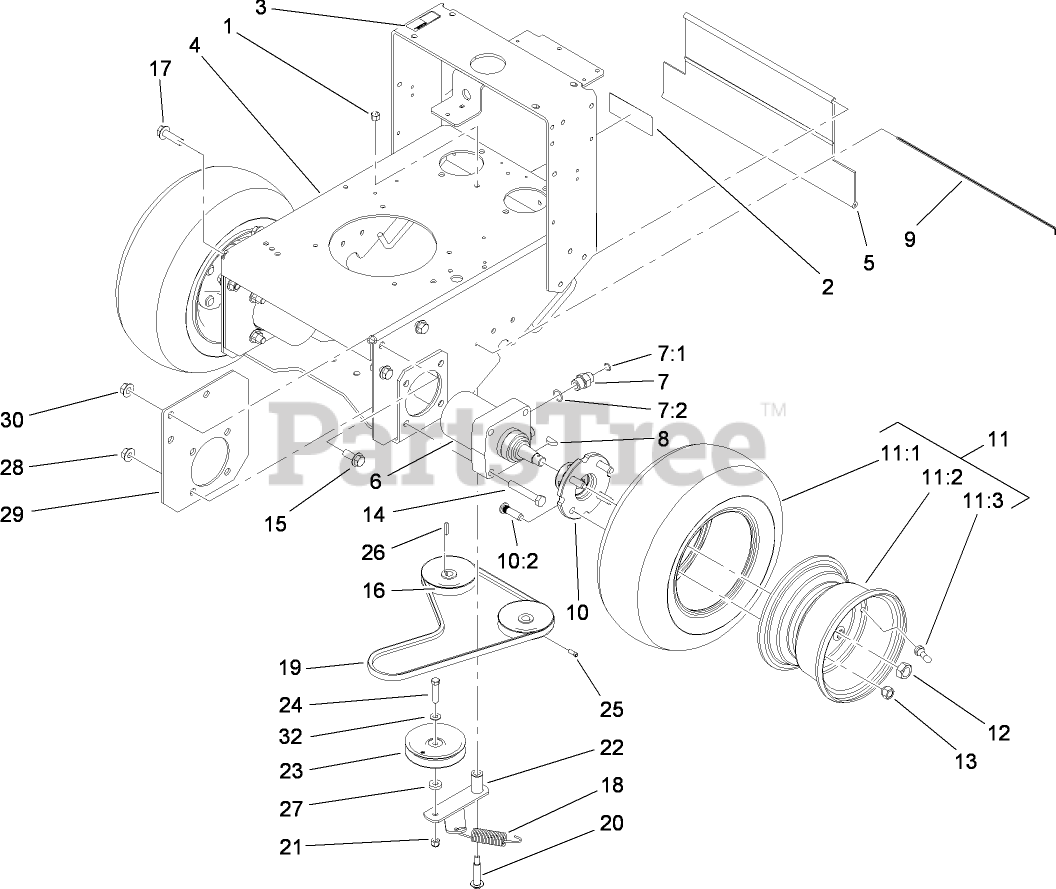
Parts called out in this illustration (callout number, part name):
1	NUT-LOCK
2	DECAL-CAUTION
3	DECAL-SHUT OFF, FUEL
4	FRAME ASM
5	SHIELD-TRAILING
6	HYD MOTOR ASM
7	FITTING-STRAIGHT
7:1	O-RING
7:2	O-RING
8	KEY-WOODRUFF
9	ROD-SHIELD
10	WHEEL HUB ASM
10:2	STUD-TYPE, DRIVE
11	WHEEL AND TIRE ASM
11:3	STEM-VALVE
12	NUT-MOTOR, WHEEL
13	NUT-LUG
14	SCREW-HH
15	SCREW-HHF
16	PULLEY-PUMP
17	SCREW-HHF
18	SPRING-TRACTION
19	BELT-V
20	BOLT-WHEEL
21	NUT-LOCK, NI
22	IDLER LEVER ASM
23	PULLEY-IDLER
24	SCREW-HH
25	SCREW-SET
27	Washer
28	NUT-HHF
29	PLATE-FRAME
30	NUT-HF
32	WASHER-FLAT
